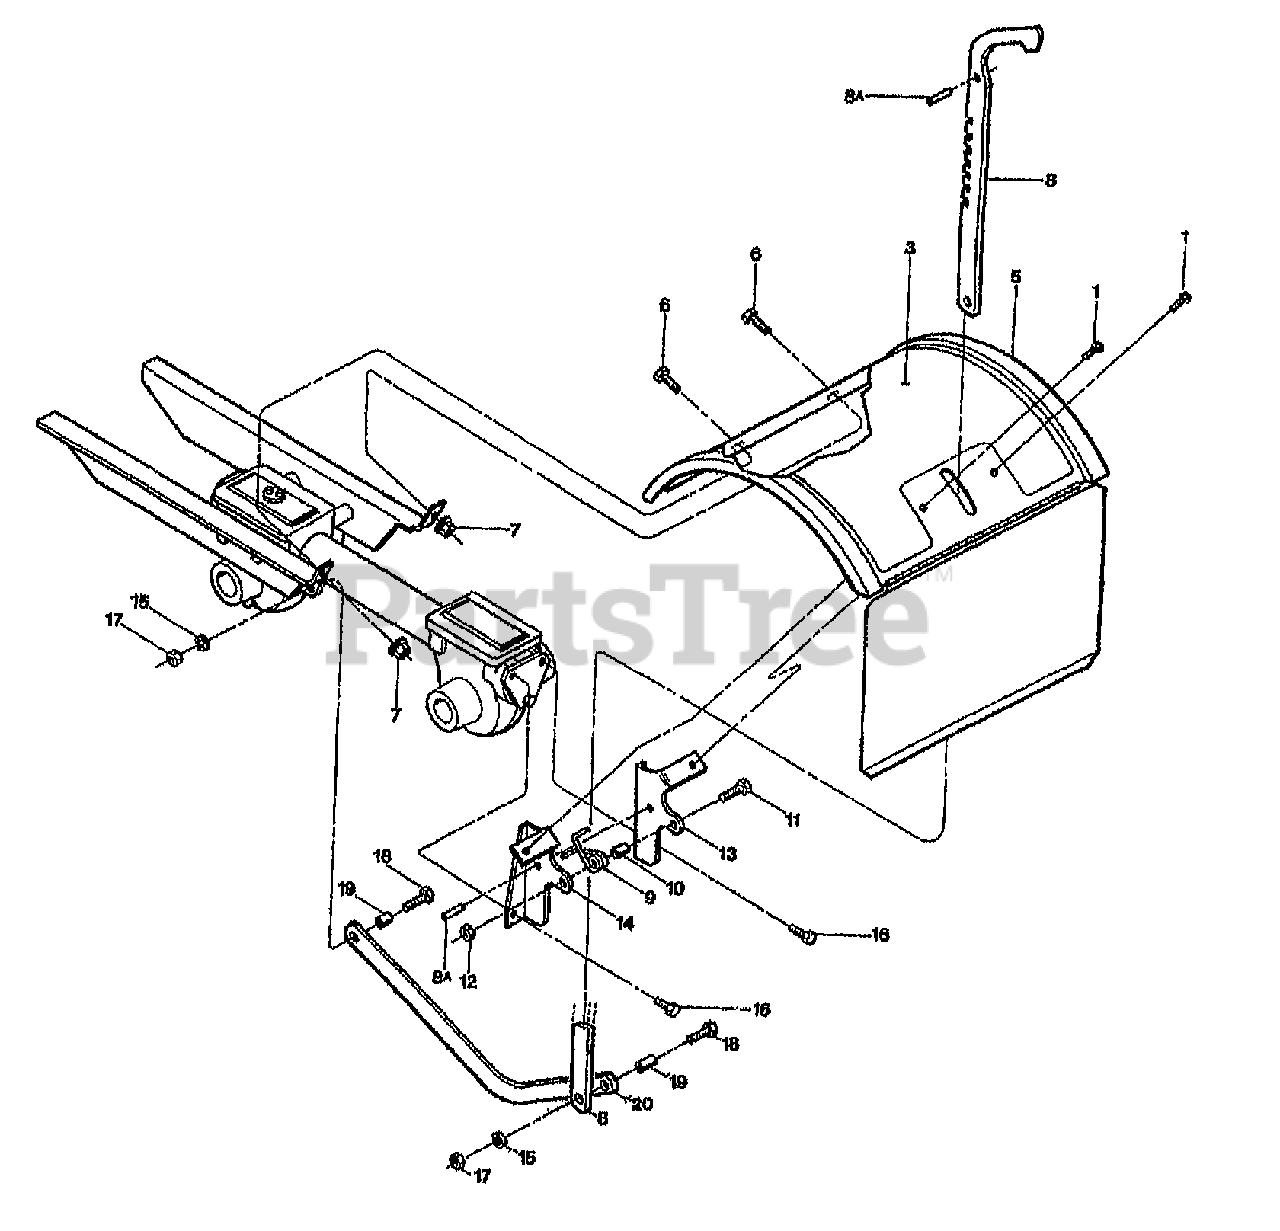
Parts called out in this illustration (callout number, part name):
1	SCR-HWH 1/4-20 X .5 STH
2	REF. NO. 2 IS NOT USED
3	DECAL-HOOD OPER INST
3	DECAL-HOOD INST TUFFY {12155}
4	REF. NO. 4 IS NOT USED
5	HOOD W/DECALS PNT (INCL. TINE FLAP & 55101)
5	HOOD W/DECALS TUFFY (INCL. TINE FLAP & 55101)
6	SCR-HH 5/16-18X.5 GD5 YEL
7	NUT-HFLK 5/16-18 ZP
8	DEPTH REG-W/PIN PNT
8A	PIN-ROLL .25 X 1
9	SPRING-TORSION
10	SPACER-.250X.343X.375
11	SCR-HH 1/4-20X1.0
12	NUT-LK 1/4-20
13	BRKT-HOOD RIGHT PNT
14	BRKT-HOOD LEFT PNT
15	WASHER-LK .312 ZP
16	SCR-HFLK 5/16-18X1.00 ZP
17	NUT-HEX 5/16-18 ZP
18	SCR-HH 5/16-18X1.25 G5ZP
19	BUSHING-.438X.323X.4
20	DRAG BAR-TUFFY PNT
